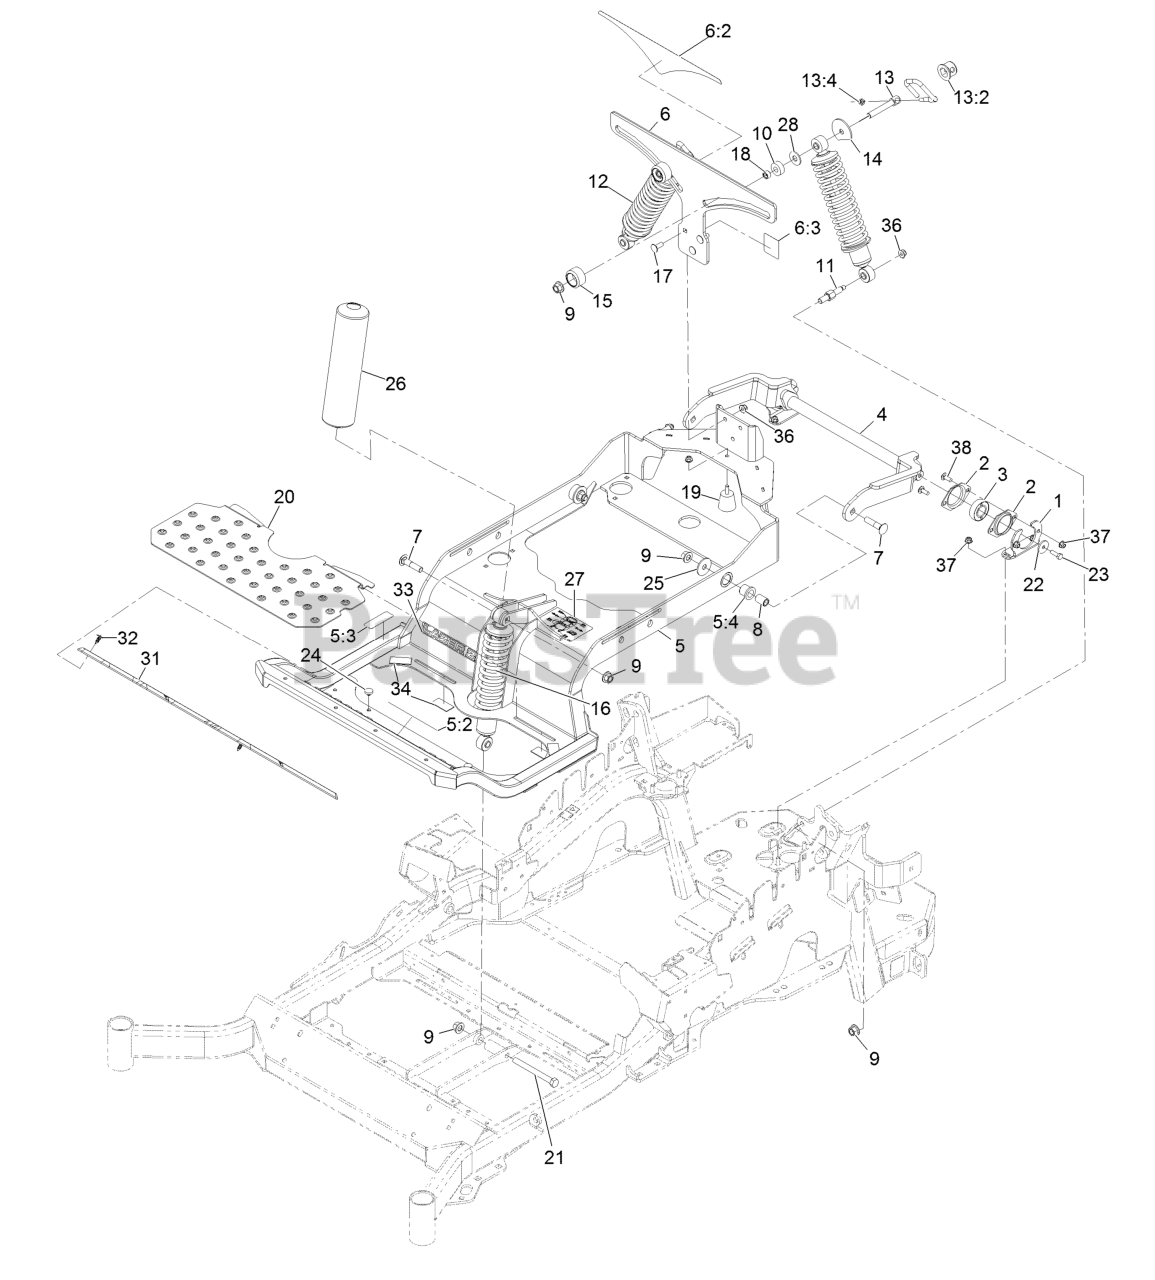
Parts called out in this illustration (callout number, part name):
1	Bracket-Bearing
2	Housing-Bearing, Flange
3	Bearing
4	Arm-Trailing
5	Subframe ASM
5:2	Decal-Danger
5:3	Decal-Brake, Parking
5:4	Bushing-Flange
6	Bracket-Mounting
6:2	Decal-Adjustment, Ride
6:3	Decal-Lock, Cam
7	Bolt-Carriage 1/2-13 X 2 1/4
8	Spacer-Aluminum
9	Nut-Lock 1/2-13
11	Bolt-Shoulder
12	Shock/Spring ASM
13	Cam Lock ASM
13:2	Cap-Lock
13:4	Nut-Hex Nyloc 5/16-18
14	Plate-Stop
15	Knob-Front
16	Shock/Spring ASM
17	Bolt-Carriage 3/8-16 X 1
18	Bearing-Needle
19	Bumper-Rubber
21	Screw-HH 1/2-13 X 5
22	Washer-Flat
23	Screw-HH 5/16-18 X 1 W/Patch
26	Cover-Shock
27	Decal-Service Aid
28	Washer
31	Floor Mat
32	Plug-Plastic
33	Decal-Lazer Logo
34	Pad-Rubber
36	Nut-Nyloc 3/8-16 Flg
37	Nut-Nyloc 5/16-18 Flg
38	Bolt-Carriage 5/16-18 X 7/8
